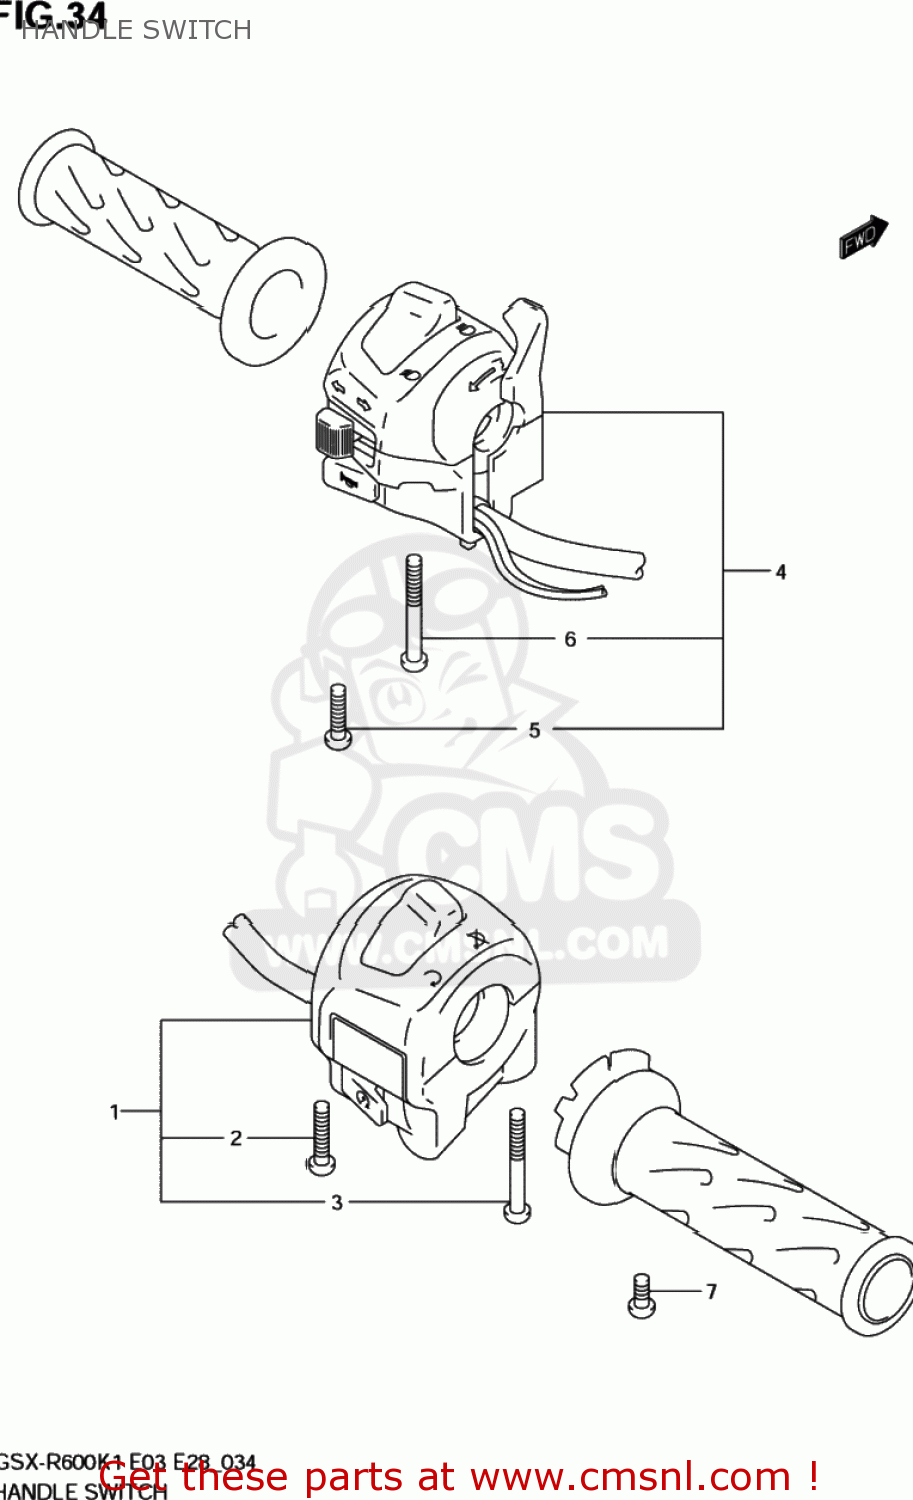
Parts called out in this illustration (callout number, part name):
1	SWITCH ASSY,HANDLE,R
2	SCREW
3	SCREW
4	SWITCH ASSY,HANDLE,L
5	SCREW
6	SCREW, 5X45
7	SCREW
